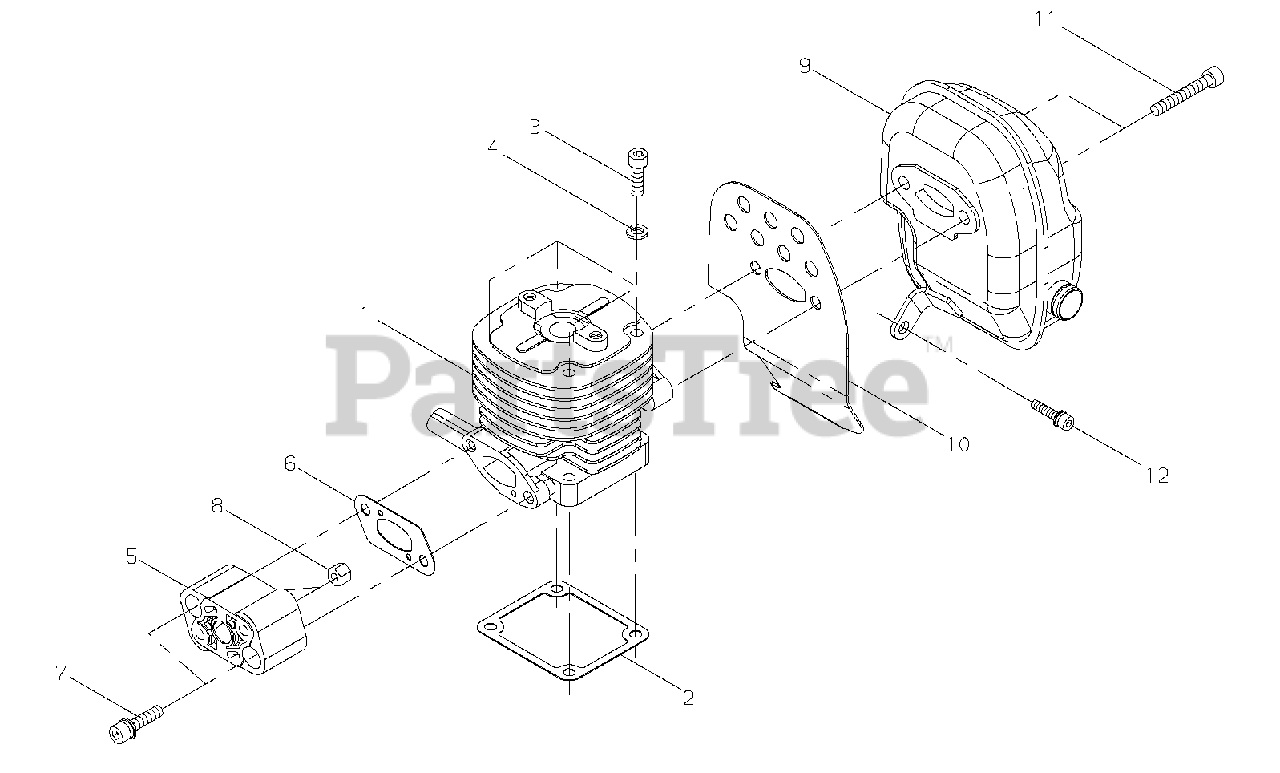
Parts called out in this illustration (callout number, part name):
1	CYLINDER
2	GASKET, CYLINDER
3	BOLT 5×25
4	WASHER, SPRING 5
5	INSULATOR, INTAKE
6	GASKET, INTAKE
7	BOLT M5×25
8	NUT M5×6.3
9	MUFFLER
10	HEAT SHIELD, EXHAUST
11	BOLT 6×25
12	BOLT M5×12
